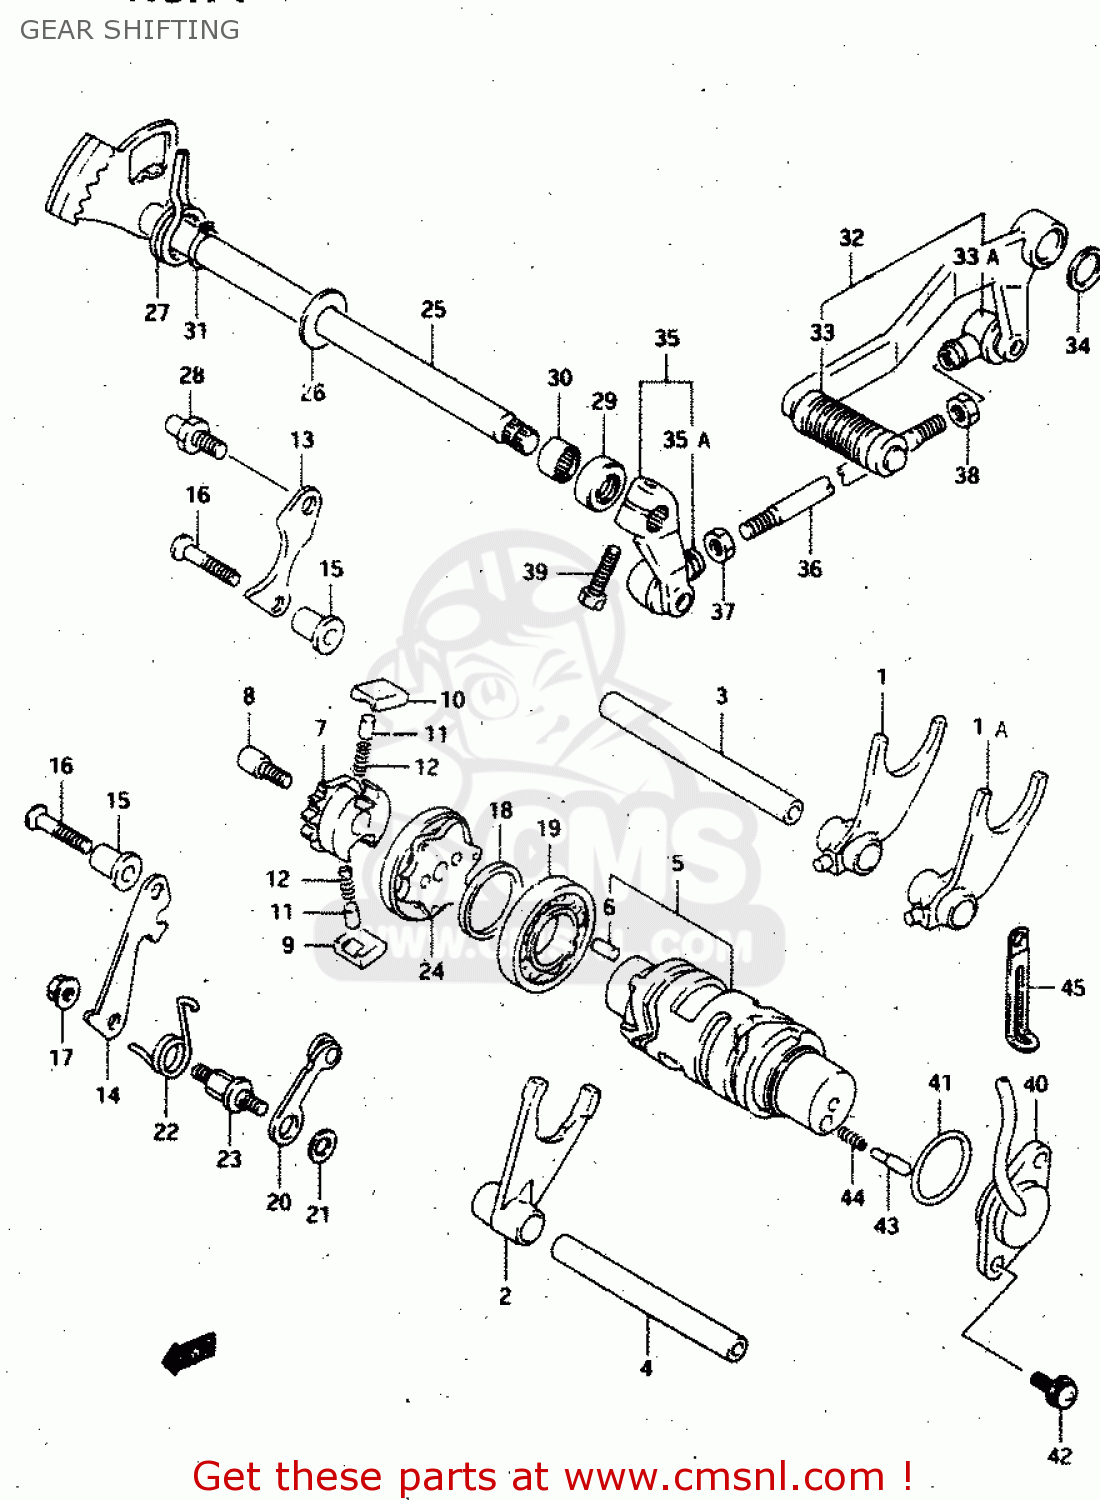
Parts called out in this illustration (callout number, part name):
1	FORK,GEAR SHIFT NO.1
1A	FORK,GEAR SHIFT NO.2
2	FORK,GEAR SHIFT NO.3
3	SHAFT,GEAR SHIFT FORK
4	SHAFT,GEAR SHIFT FORK
5	CAM,GEAR SHIFT
6	PIN
7	GEAR,GEARSHIFT CAM DRIVE
8	PIN,SHIFT CAM DRIVEN GEAR
9	PAWL,GEAR SHIFT NO.1
10	PAWL,GEAR SHIFT NO.2
11	PIN(5X8)
12	SPRING
13	LIFTER,GEAR SHIFT POLE
14	GUIDE,GEAR SHIFT CAM
15	SPACER(6.1X10X16)
16	SCREW
17	NUT
18	WASHER(25X32X3)
19	BEARING
20	STOPPER,SHIFT CAM
21	WASHER
22	SPRING, STOPPE
23	SUPPORT,CAM STOPPER ARM
24	PLATE,GEAR SHIFT CAM
25	SHAFT,GEAR SHIFT
26	WASHER,THRUST
27	SPRING
28	STOPPER,GEAR SHIFT ARM
29	SEAL,OIL(14X22X6)
30	BEARING(14X20X12)
31	CIRCLIP
32	LEVER ASSY,GEAR SHIFT
33	RUBBER,GEAR SHIFT PEDAL
33A	COVER,DUST
34	WASHER
35	ARM,GEAR SHIFT LINK
35A	COVER,DUST
36	ROD,GEAR SHIFT LINK
37	NUT
38	NUT
39	BOLT
40	BASE,SHIFT TER
41	O-RING (D:2.4 ID:26.2)
42	SCREW
43	PIN(5X15.5)
44	SPRING
45	CLAMP
